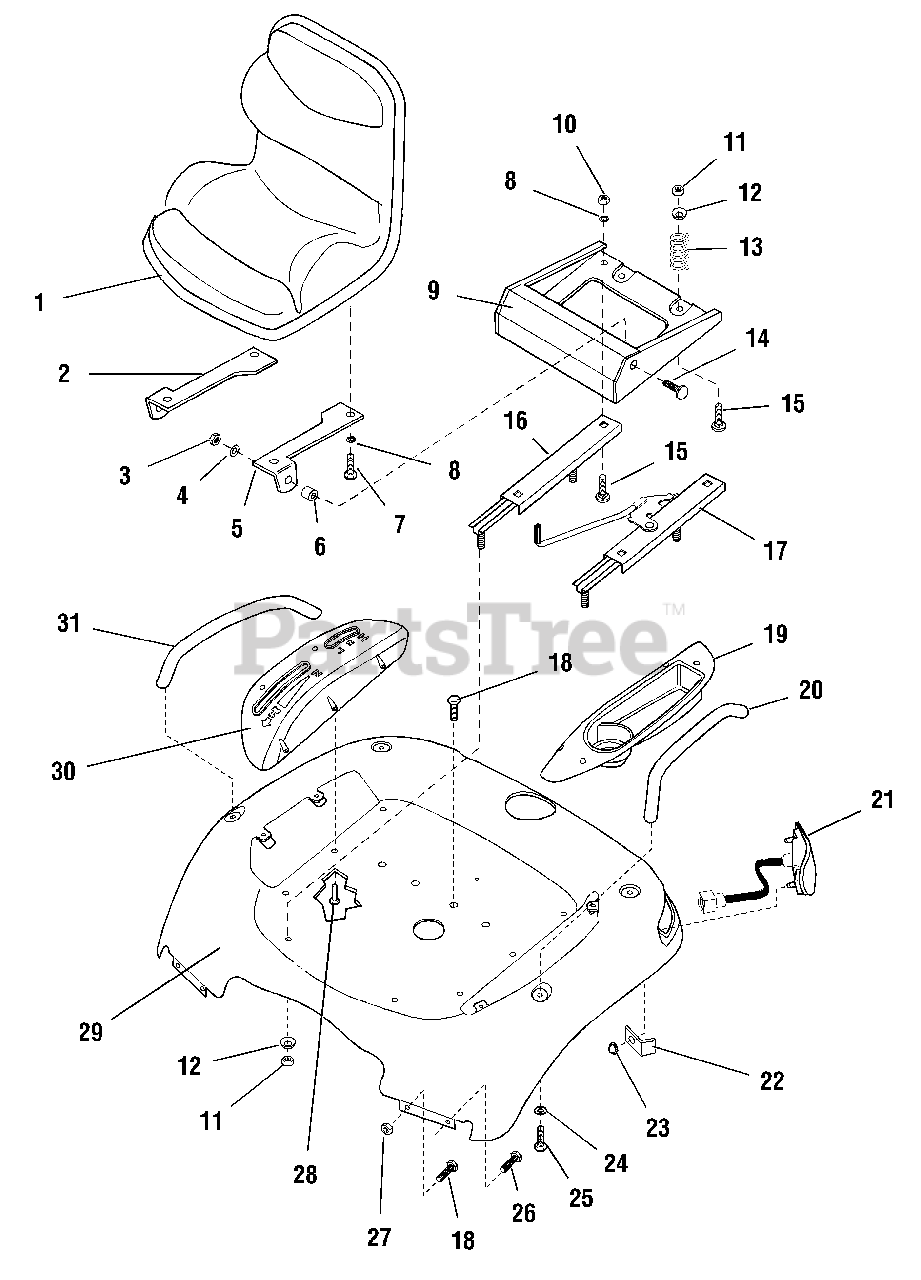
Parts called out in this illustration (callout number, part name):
2	SEAT BRACKET, RH
3	NUT, Hex, Nylon Lock, 3/8-16
4	WASHER, Plain, 3/8
5	SEAT BRACKET, LH
7	CAPSCREW, Hex Hd, 1/4-20 x 5/16
8	LOCKWASHER, 5/16
9	BRACKET, Seat Support
10	NUT, Hex, Full, 5/16-18
11	NUT, Hex, Nylon Lock, 5/16-18
12	WASHER, Bell
13	SPRING, Seat
14	CARRIAGE BOLT, 3/8-16 x 1
15	CARRIAGE BOLT, 5/16-18 x 3/4
16	SLIDER ASSEMBLY, RH, Slave
17	SLIDER ASSEMBLY, LH, Main
18	CAPSCREW, Hex Hd, Taptite, 5/16-18 x 3/4
19	CUPHOLDER POD
21	TAIL LIGHT, Assembly
23	NUT, Push, 5/16
24	WASHER, 5/16
25	CAPSCREW, Hex Hd, 5/16-18 x 1/2
26	CAPSCREW, Hex Flange, 5/16-18 x 1/2
27	NUT, Hex, Whizlock, 5/16-18
28	CAPSCREW, #12-24 x 5/16
29	SEAT DECK (Orange)
29	SEAT DECK (Red)
30	CONTROL POD
